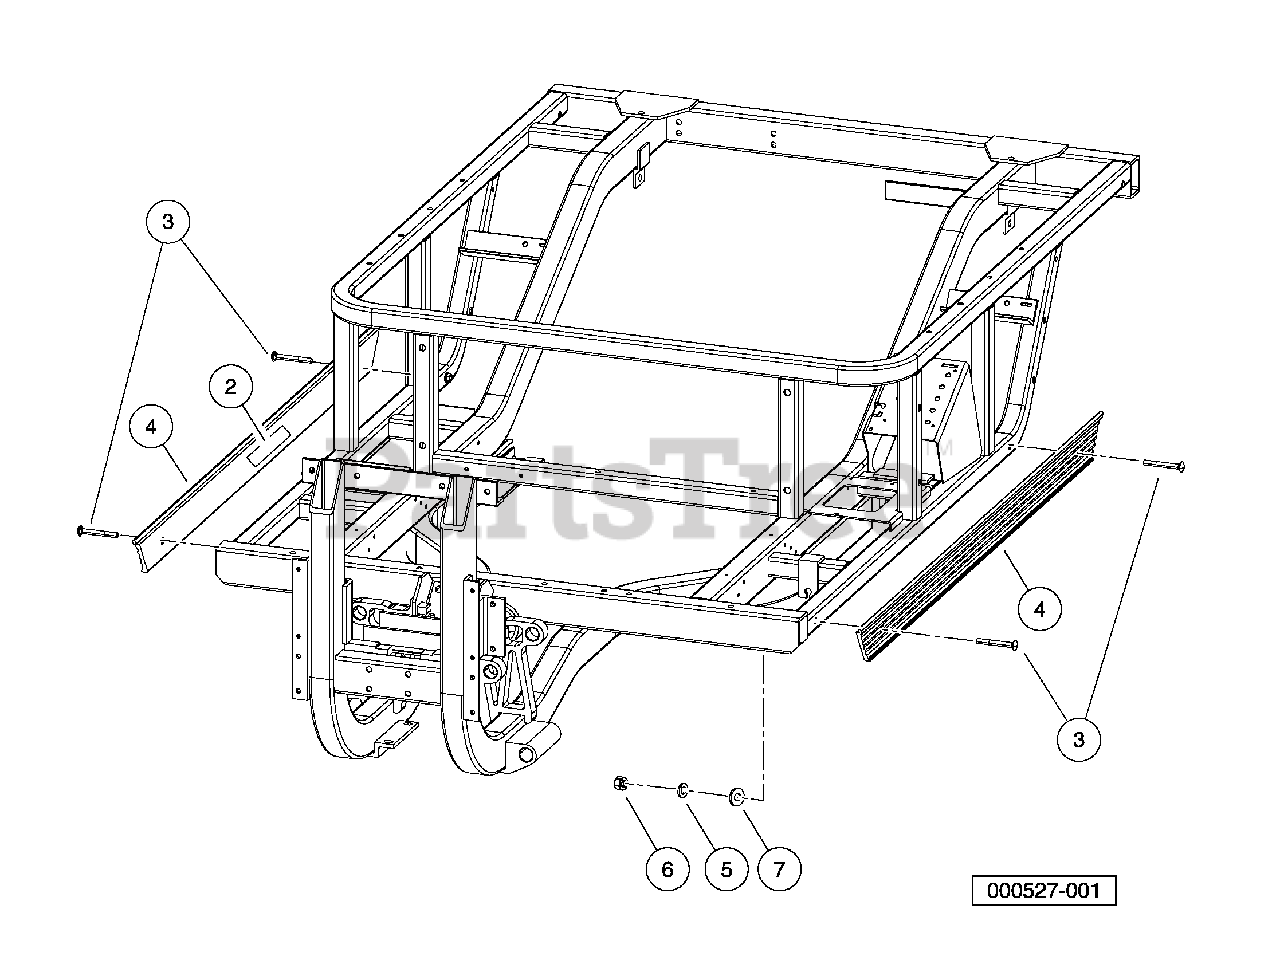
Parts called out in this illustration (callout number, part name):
1	Instl, Stringer, Black
2	Tape, 3M VHB 4950
3	Bolt, 3/8-16 X 3, Carriage Blk
4	Stringer, Side, 1349.25, Black
5	Washer, Lock, Hel Sp 3/8 Reg
6	Nut, Hex 3/8-16
7	Washer, 3/8 Type B Flat
